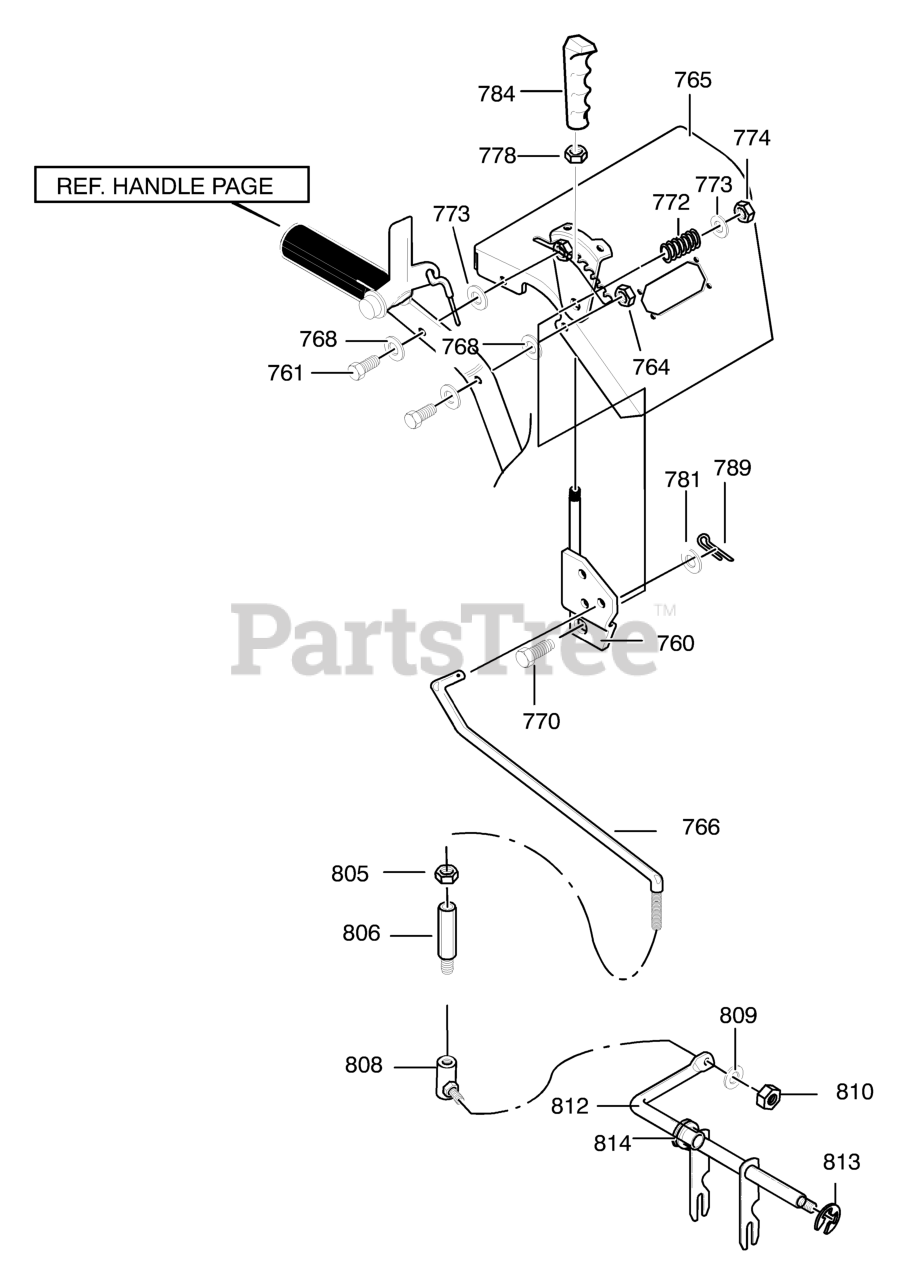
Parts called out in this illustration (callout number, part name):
760	HANDLE ASSY SPD CTRL
761	SCREW, 5/16-18 x 1.75
764	NUT, 5/16-18
765	ASSY. BAYPANEL -LT
766	ROD, SPEED CONTROL
768	WASHER
770	SCREW 3/8-16X2.00
773	FLATWASHER
774	NUT, 3/8-16
778	NUT, 3/8-16
781	FLATWASHER
784	HANDLE, GRIP
789	PIN, COTTER
805	NUT, 5/16-18
806	ADAPTER, SPEED ROD -YZ
808	BALLJOINT, STEEL -YZ
809	WASHER
810	NUT, 5/16-18
812	ROD, ASSY YOKE
813	RING, RETAINER
814	BEARING, FLANGE
